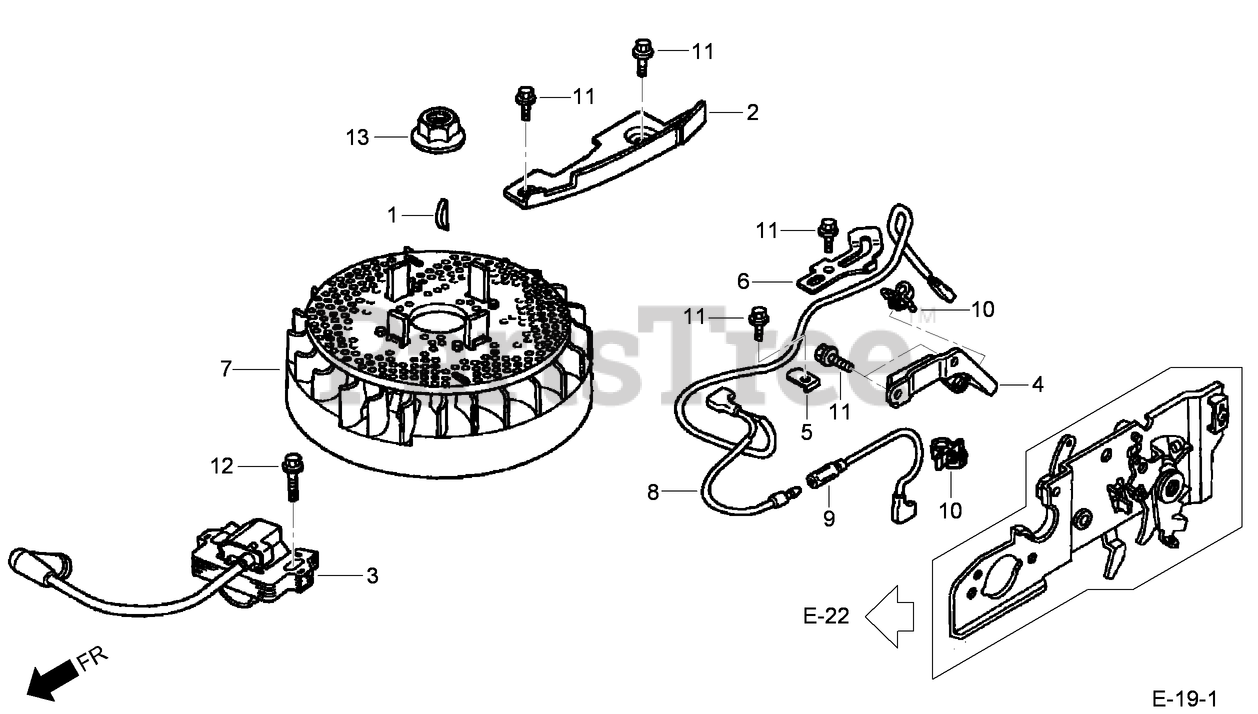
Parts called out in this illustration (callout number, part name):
1	KEY-WOODRUFF, SPECIAL (25X18)
2	PLATE-SIDE (engine serial numbers up to 5008780)
2	PLATE-SIDE (engine serial numbers starting at 5008781)
3	IGNITION COIL ASM (PHELON) (USE FOR FLYWHEEL OF PHELON)
4	CLAMP-WIRE, STOP SWITCH
5	CLAMP-WIRE, STOP SWITCH
6	CLAMP-WIRE
7	FLYWHEEL ASM (PHELON) (USE FOR IGNITION COIL OF PHELON)
8	WIRE-SWITCH, STOP
9	WIRE-SWITCH, STOP
10	HOLDER-WIRE (FASTEX)
10	CLIP A-CABLE (3.8MM BLACK) (NIFCO)
11	BOLT-FLANGE (6X12) (C T200)
12	BOLT-FLANGE (6X20) (C T200) (engine serial numbers up to 6702082)
13	NUT-SPECIAL (14 mm)
